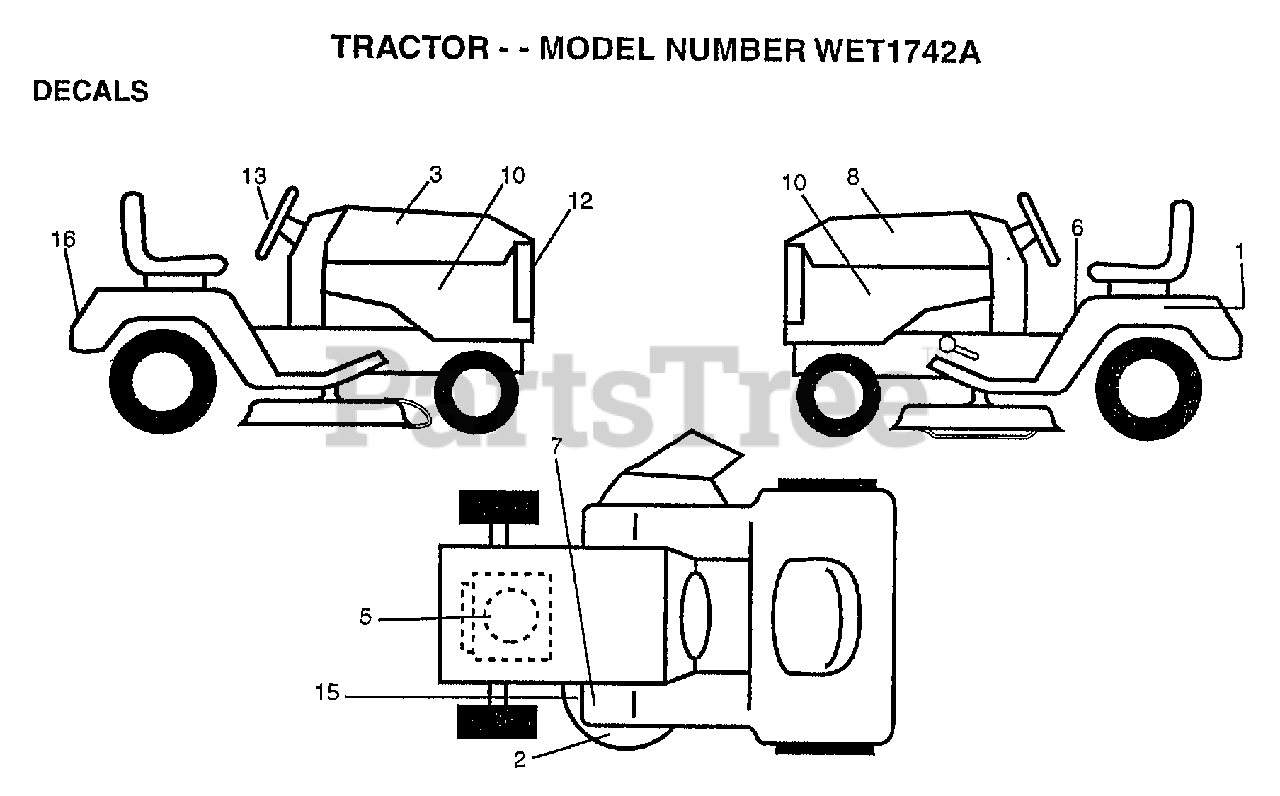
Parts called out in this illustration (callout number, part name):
1	DECAL.BATRY.3-3908
3	DECAL HOOD RH
6	"DECAL DANGER,FEND"
8	DECAL HOOD LH
10	DECAL PANEL SD
12	"DECAL GRILLE,LENS"
13	"DECAL INS,STRG WH"
15	DECAL
16	DECAL-FENDER
19	"DECAL DASH,OPER."
